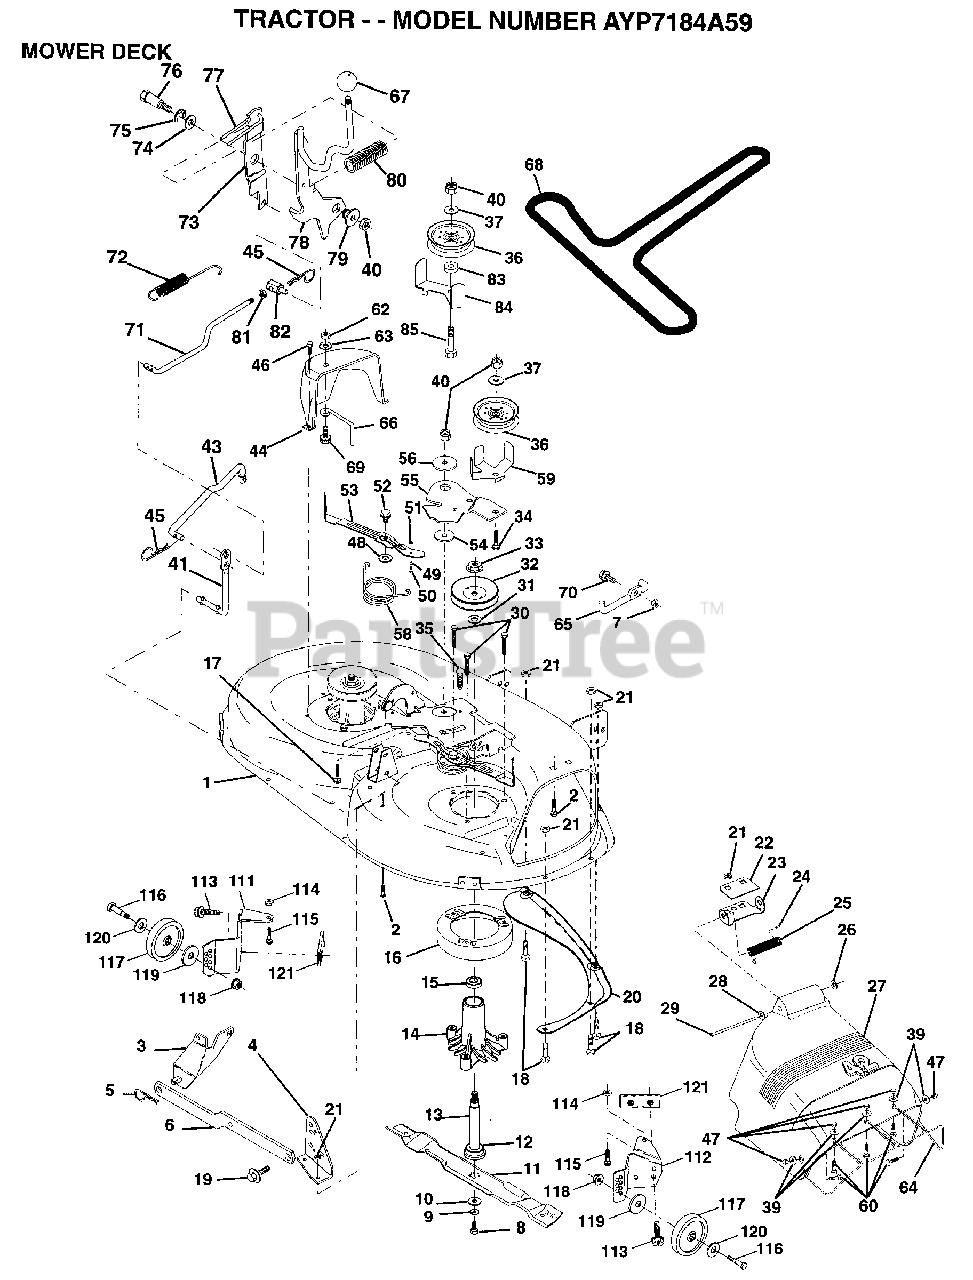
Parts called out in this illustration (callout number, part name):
1	DECK.WELD.42.
2	BOLT
3	BRKT ASM SWAY BAR
4	BRKT DECK SW BAR
8	BLADE BOLT
10	WASHER.HARD.BLADE
11	"BLADE.42"" MULCHER"
12	BEARING.BALL
14	HSG ASM MANDREL
15	BEARING
16	STRIPPER RND MWR
17	BOLT RDHD 3/8-16
18	BOLT
19	BOLT SHD 5/16-18
22	STIFFENER BRKT
23	DEFLECTOR BRKT
24	CAP-SLEEVE LT
25	SPRING TORSION
26	NUT PUSH M
27	DEFLECTOR.SHIELD
28	WASHER
29	HINGE ROD
31	WASHER
34	BOLT
35	XMAS TREE FASTNER
36	FLAT IDLER PULLEY
37	WASHER
41	PIVOT ROD
43	ROD CLUTCH W/NIBS
44	GUARD MAND LH BLK
45	RETAINER M
46	SCREW.1/4-20X5/8
48	HARD SMALL WASHER
50	SHOULDER BOLT
51	LOCKNUT
52	BOLT.SHLD.5/16-18
53	BRAKE PAD ARM ASM
54	HARDENED WASHER
56	SPACER RETAINER
58	SPRING TORSN BRAK
59	GUARD IDLER TUV
67	KNOB T (1/2-HOLE)
68	BELT.V.T-PATH
71	ROD CLUTCH 38/42
72	RETURN SPRING
73	CLUTCH ARM SECOND
74	WASHER
75	RING
76	SHOULDER BOLT
77	SPRING KEEPER
78	LEVER ASM CLT PRM
79	BUSHING
81	NUT
82	TRUNION ADJ
83	WASHER
85	BOLT
113	SCREW
116	BOLT M
117	WHEEL.GAGE.BLK.PL
118	LOCKNUT
119	WASHER
120	WASHER
121	BRACKET.EXTRD.GWL
